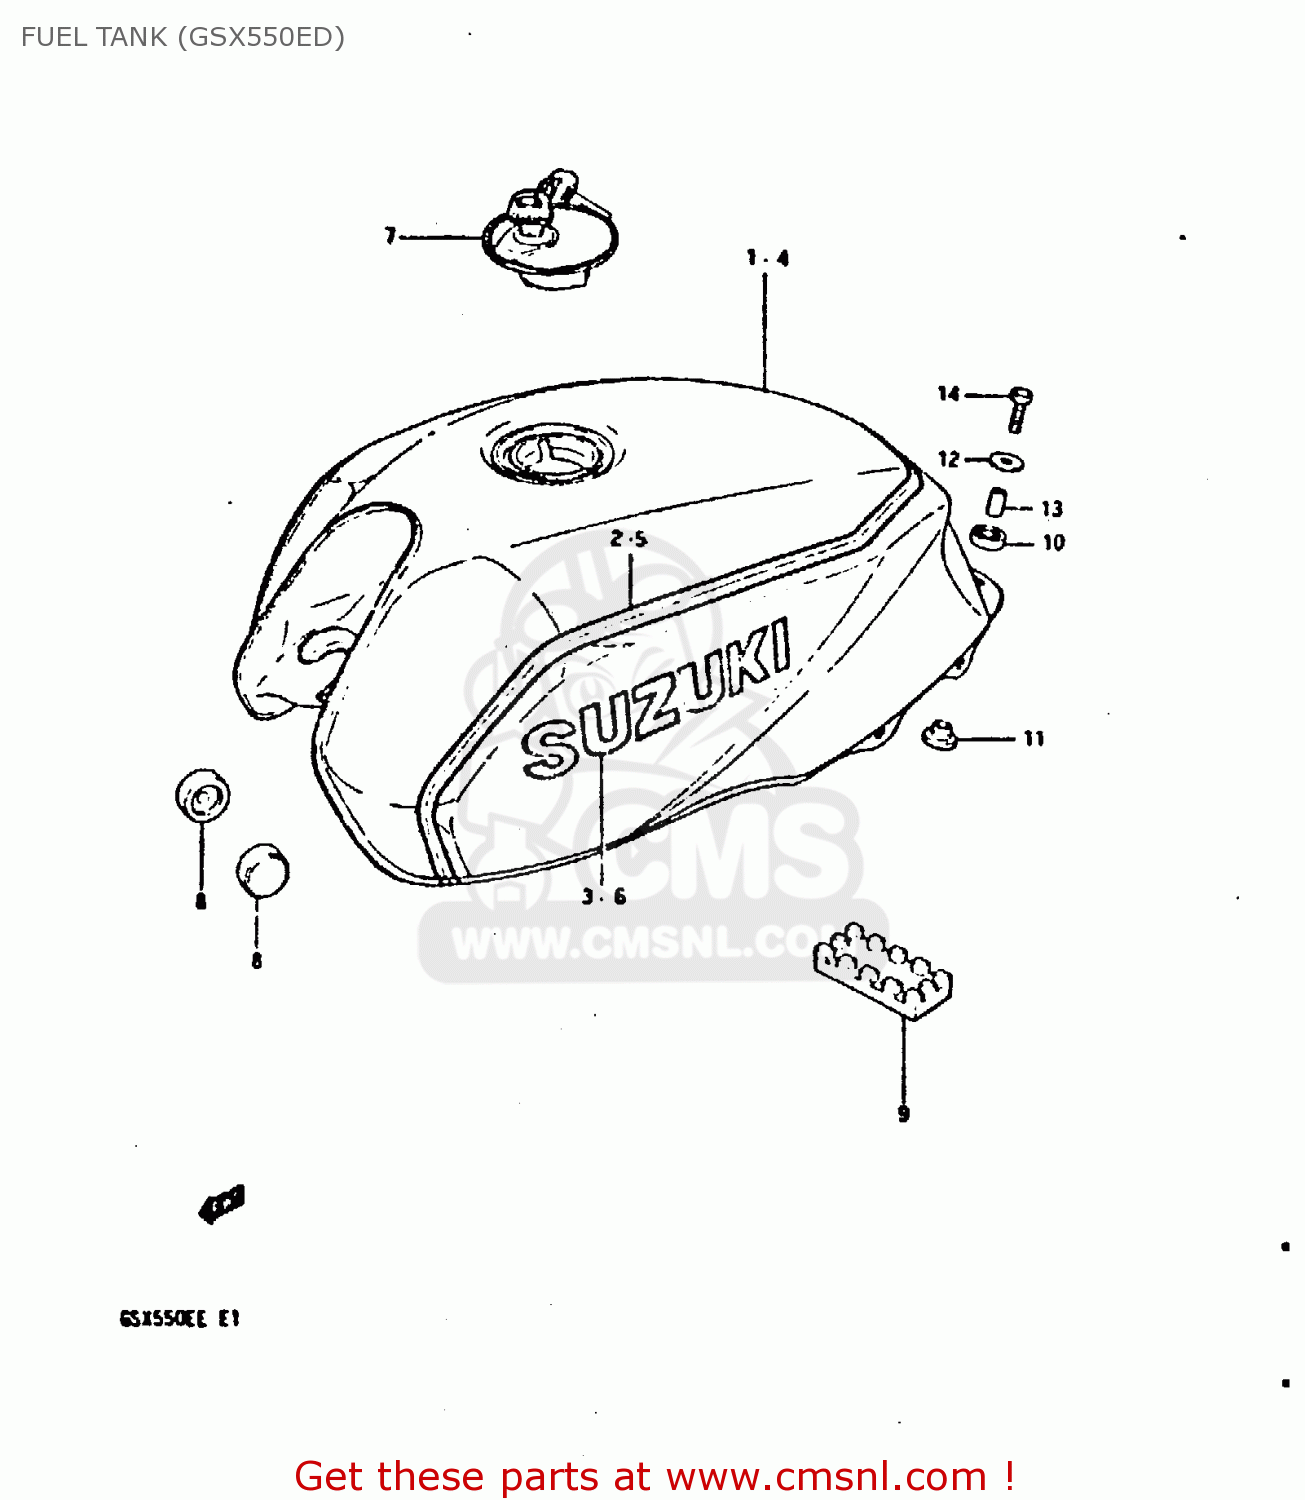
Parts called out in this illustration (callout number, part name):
1	TANK, FUEL
2	TAPE SET,FUEL TANK
3	EMBLEM
4	TANK ASSY, FUEL
5	TAPE SET,FUEL TANK
6	EMBLEM
7	CAP SET,FUEL TANK
8	CUSHION
9	CUSHION,FUEL TANK
10	CUSHION
11	CUSHION
12	WASHER (6.5X24X1.6)
13	SPACER (6.4X9X20)
14	BOLT
